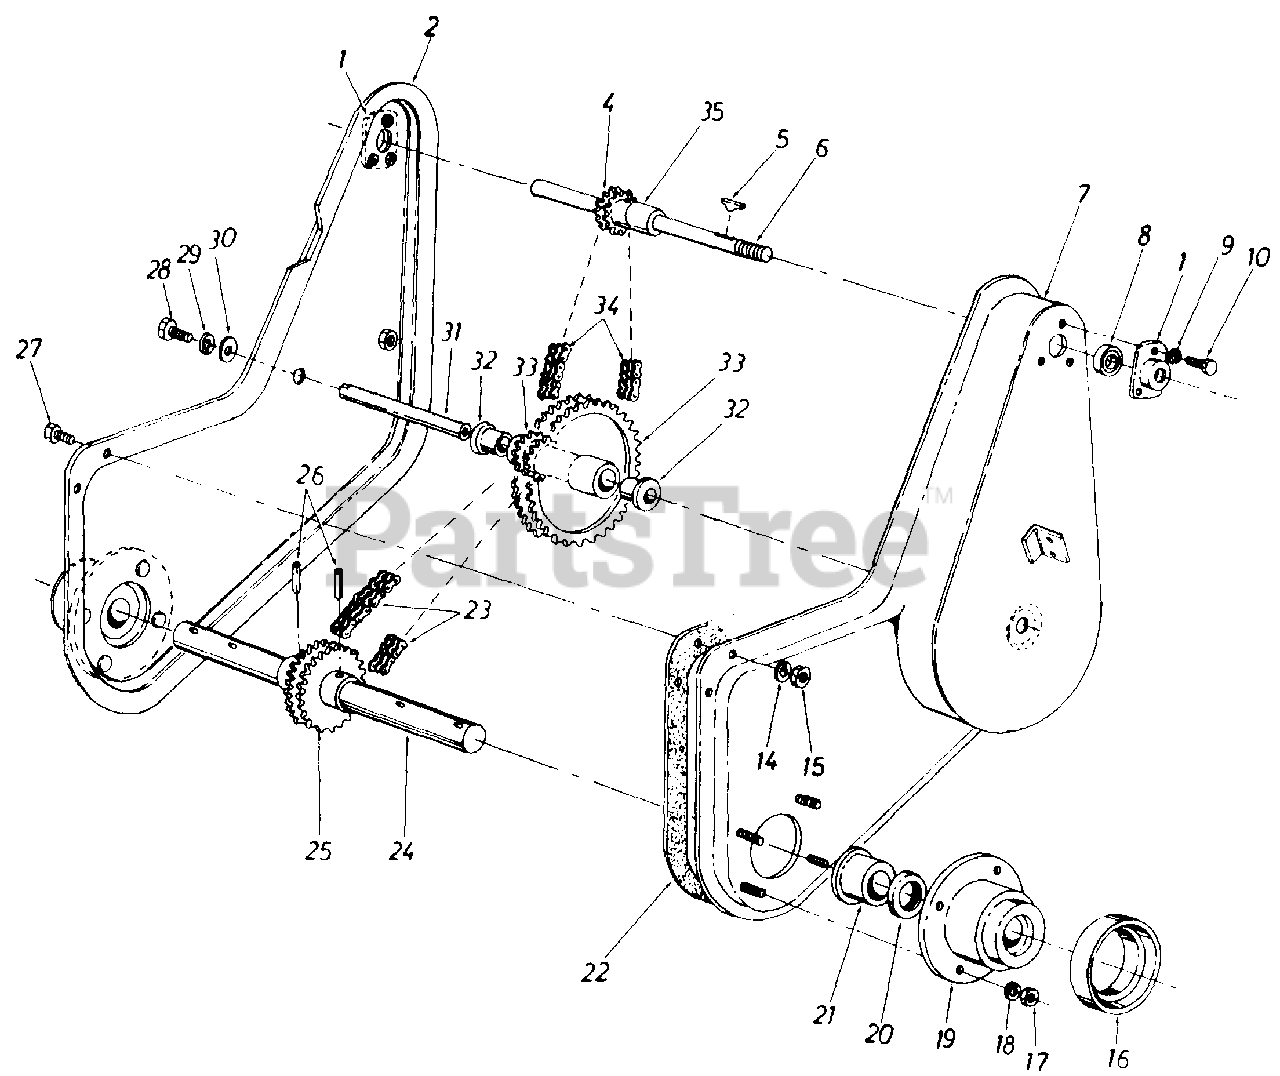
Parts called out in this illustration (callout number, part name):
1	Bearing Housing 1.375" Dia.
5	#6 Hi-Pro Key 5/32" x .62" Lg.
6	Input Shaft Assembly
9	L-Wash. 1/4" I.D.
10	Hex Bolt 1/4-20 x .62" Lg."
14	L-Wash. 1/4" I.D.
15	Hex Cent. L-Nut 1/4-20 Thd.
16	Dust Cap Cover
17	Hex Cent. L-Nut 5/16-18 Thd.
18	L-Wash. 5/16" I.D.
19	Cast Bearing Housing
20	Oil Seal
21	Flange Bearing 1.25" I.D. x 1.75" 0 D.
22	Gasket
23	Roller Chain 040-2 x 34.0" Lg.
24	Tine Shaft
25	Double Sprocket T24-2 Teeth 1/2" Pitch
26	Spiral Pin 3/8" Dia. x 2.00" Lg.
27	Hex Bolt 1/4-20 x .62" Lg.
28	Hex Bolt 5/16-18 x .75" Lg."
29	L-Wash. 5/16" I.D.
30	Fl-Wash. 5/16" I.D.
31	Sprocket Shaft
32	Flange Bearing .62" I.D. x .75" O.D.
33	Double Sprocket Assembly
34	Roller Chain #35-2 x 36.75" Lg.
35	Spacer 5/8" I.D. x 7/8" O.D.
14895-0637	Housing Assembly R.H. - POWDER BLACK (0637)
